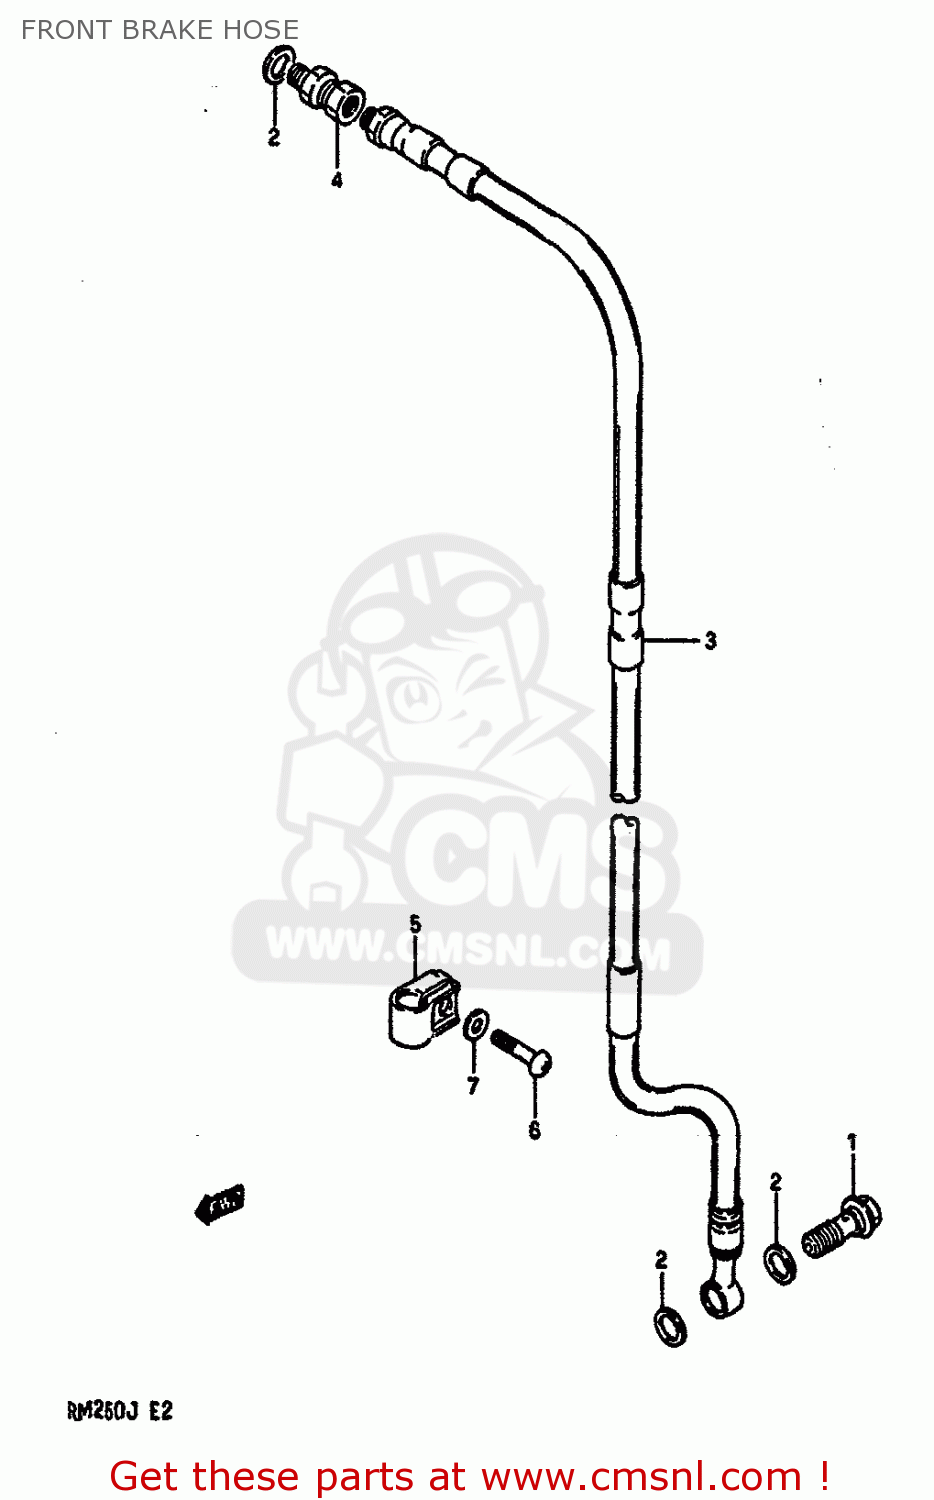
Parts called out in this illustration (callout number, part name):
1	BOLT UNION
2	WASHER(10X15X1.5)
3	HOSE,FRONT BRAKE
4	ADAPTER,BRAKE HOSE
5	CLAMP,FRONT BRAKE HOSE
6	SCREW
7	WASHER
